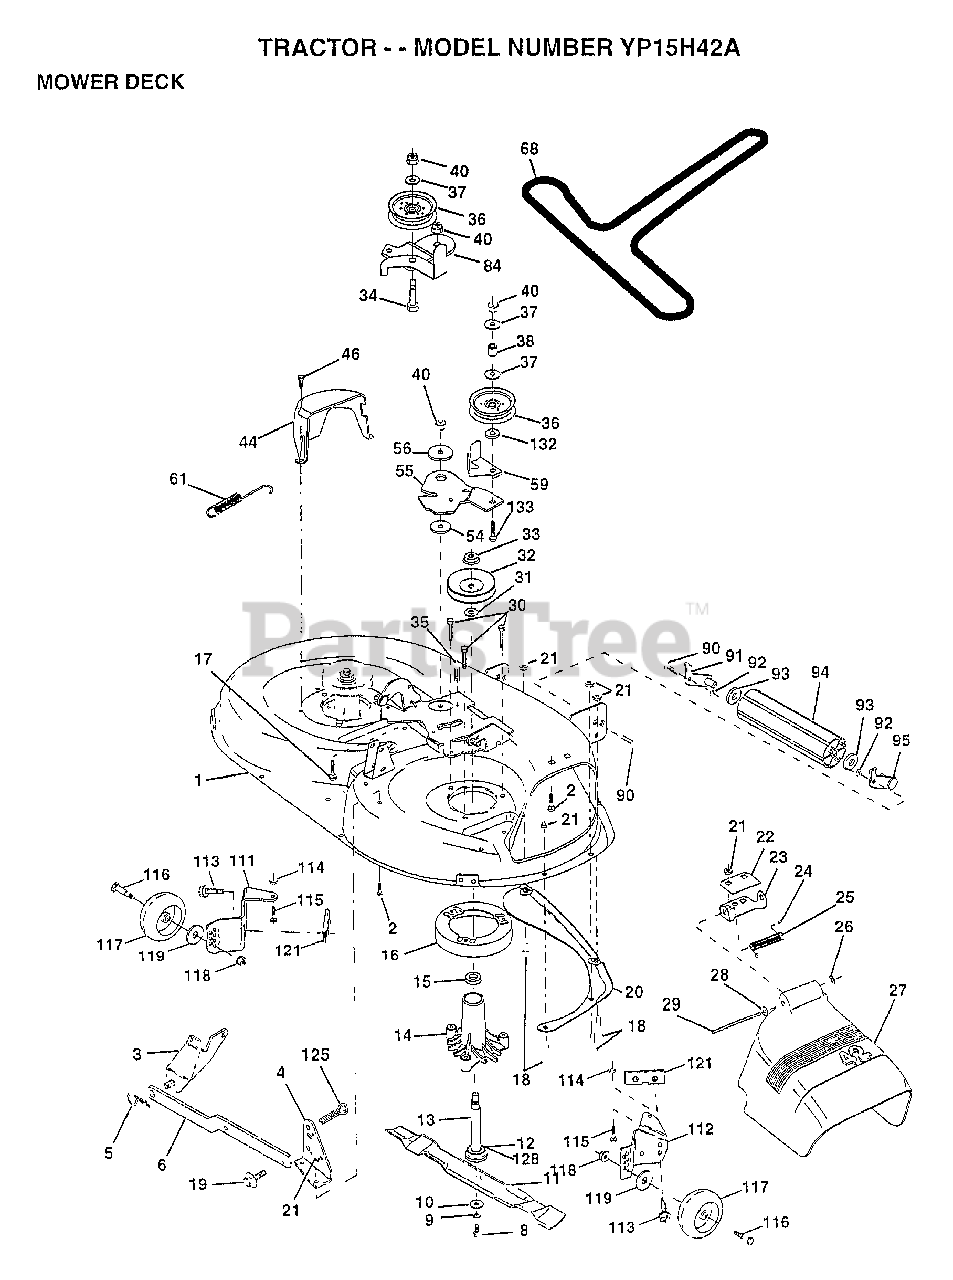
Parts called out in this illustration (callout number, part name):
1	DECK.WELD.42.
2	BOLT
3	BRKT ASM SWAY BAR
4	BRKT DECK SW BAR
8	BLADE BOLT
10	WASHER.HARD.BLADE
11	"BLADE.42"" HIPERF"
12	BEARING.BALL
14	HSG ASM MANDREL
15	BEARING
16	STRIPPER RND MWR
17	BOLT CARRIAGE
18	BOLT
19	BOLT SHD 5/16-18
22	STIFFENER BRKT
23	DEFLECTOR BRKT
24	CAP-SLEEVE LT
25	SPRING TORSION
26	NUT PUSH M
27	DEFLECTOR.SHIELD
28	WASHER
29	HINGE ROD
31	WASHER
32	PULLEY.MANDREL.42
34	BOLT
35	XMAS TREE FASTNER
36	FLAT IDLER PULLEY
37	WASHER
44	GUARD MAND LH BLK
46	SCREW.1/4-20X5/8
54	HARDENED WASHER
56	SPACER RETAINER
59	GUARD IDLER TUV
61	SPRING.EXTENSION
68	BELT-V.SEC.46.KEL
84	BRACKET ASM IDLER
90	BOLT
92	NUT
93	WASHER
111	BRACKET.GWHL.LH.
112	BRACKET.GWHL.RH.
113	SCREW
116	BOLT.SHOULDER
117	WHEEL GAGE DONUT
118	LOCKNUT
119	WASHER
121	BRACKET.EXTRD.GWL
128	WASHER.FELT.
132	WASHER GT
133	BOLT
